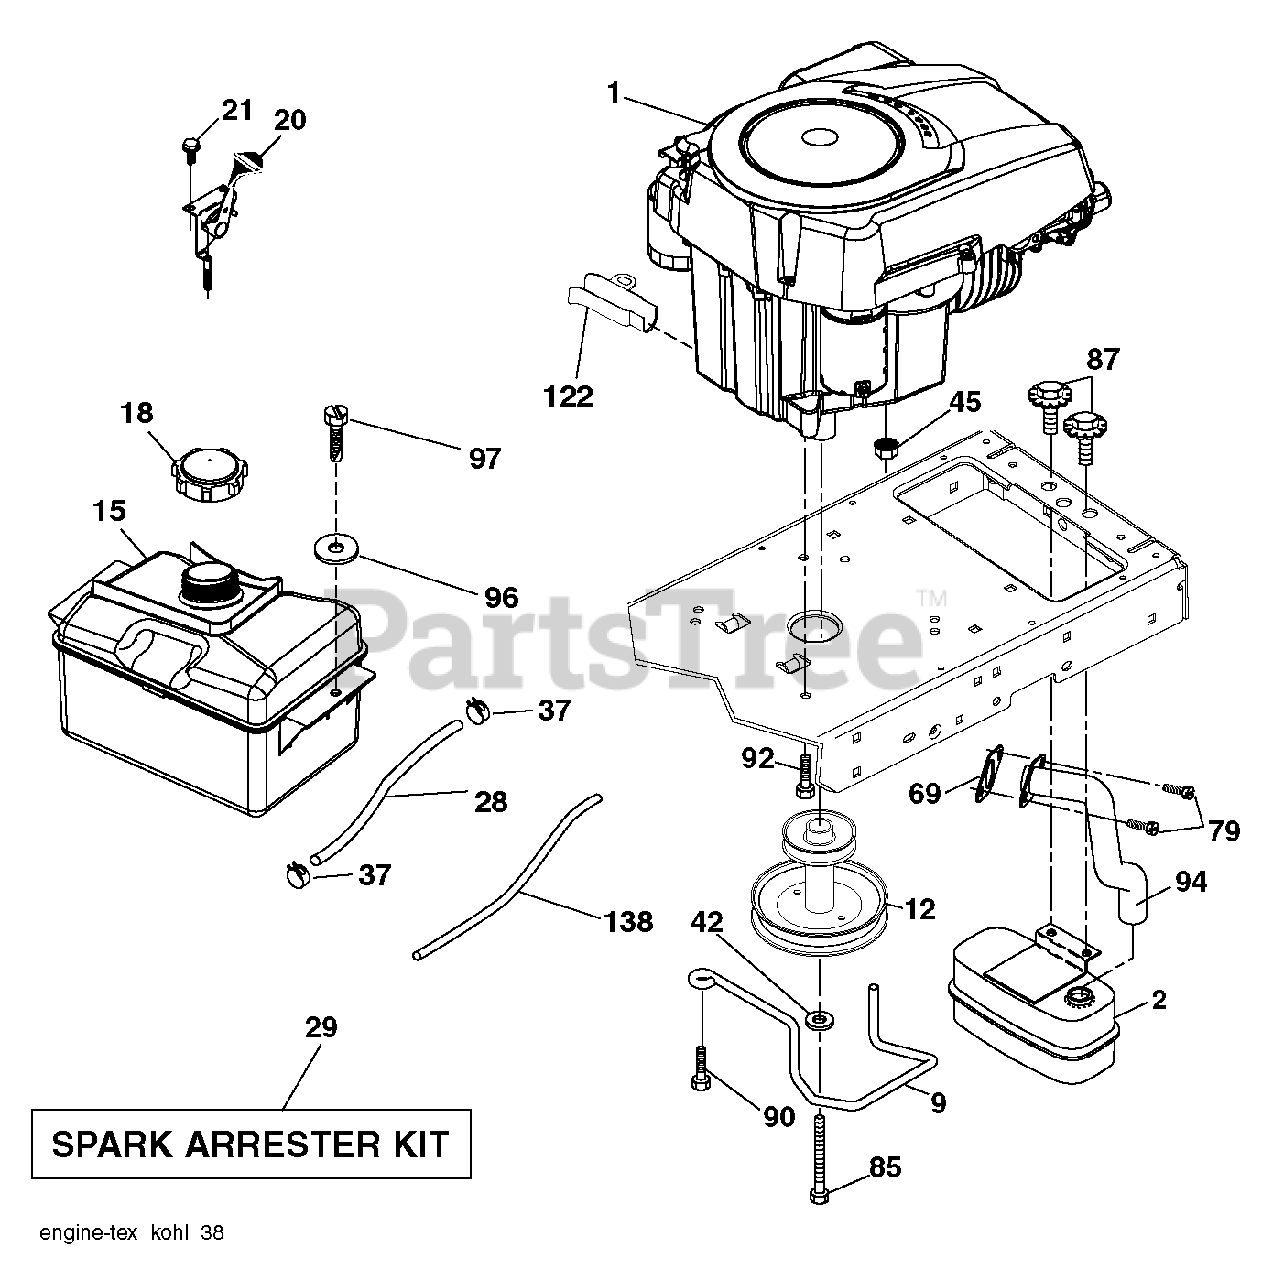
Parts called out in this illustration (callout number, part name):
2	MUFFLER.SINGLE.CYL.KOHL/B&S
9	KEEPER.BELT.ENGINE.3.25 (3 2)
12	PULLEY ENGINE
15	TANK.ASM.FRT.2.5 GAL.W/CAP.EPA
18	CAP.2.25'.VENTED.TETHER .EPA
20	CONTROL.TH/CK.COBRA.KO
21	SCREW.#10 X 0.750.BOS
28	LINE.FUEL.20"FRONT.EMI
29	SPARK ARRESTOR KIT
37	HOSE CLAMP
42	LOCKWASHER
45	NUT
69	GASKET.EXHAUST.KOHLER
79	SCREW.SOCKET HD.5/16-1
85	BOLT HEX 7/16-20X4-1/4"
87	BOLT, 5/16-18 X 1 3/4
90	SCREW 3/8-16X1
92	SCREW 3/8-16X1
94	RP.TUBE.EXHAUST.KOHL.COURAGE
96	WASHER
97	SCREW HEXWSHR 1/4-20X3/4
122	EXTENSION DRAIN OIL
138	RP PURGE LINE
